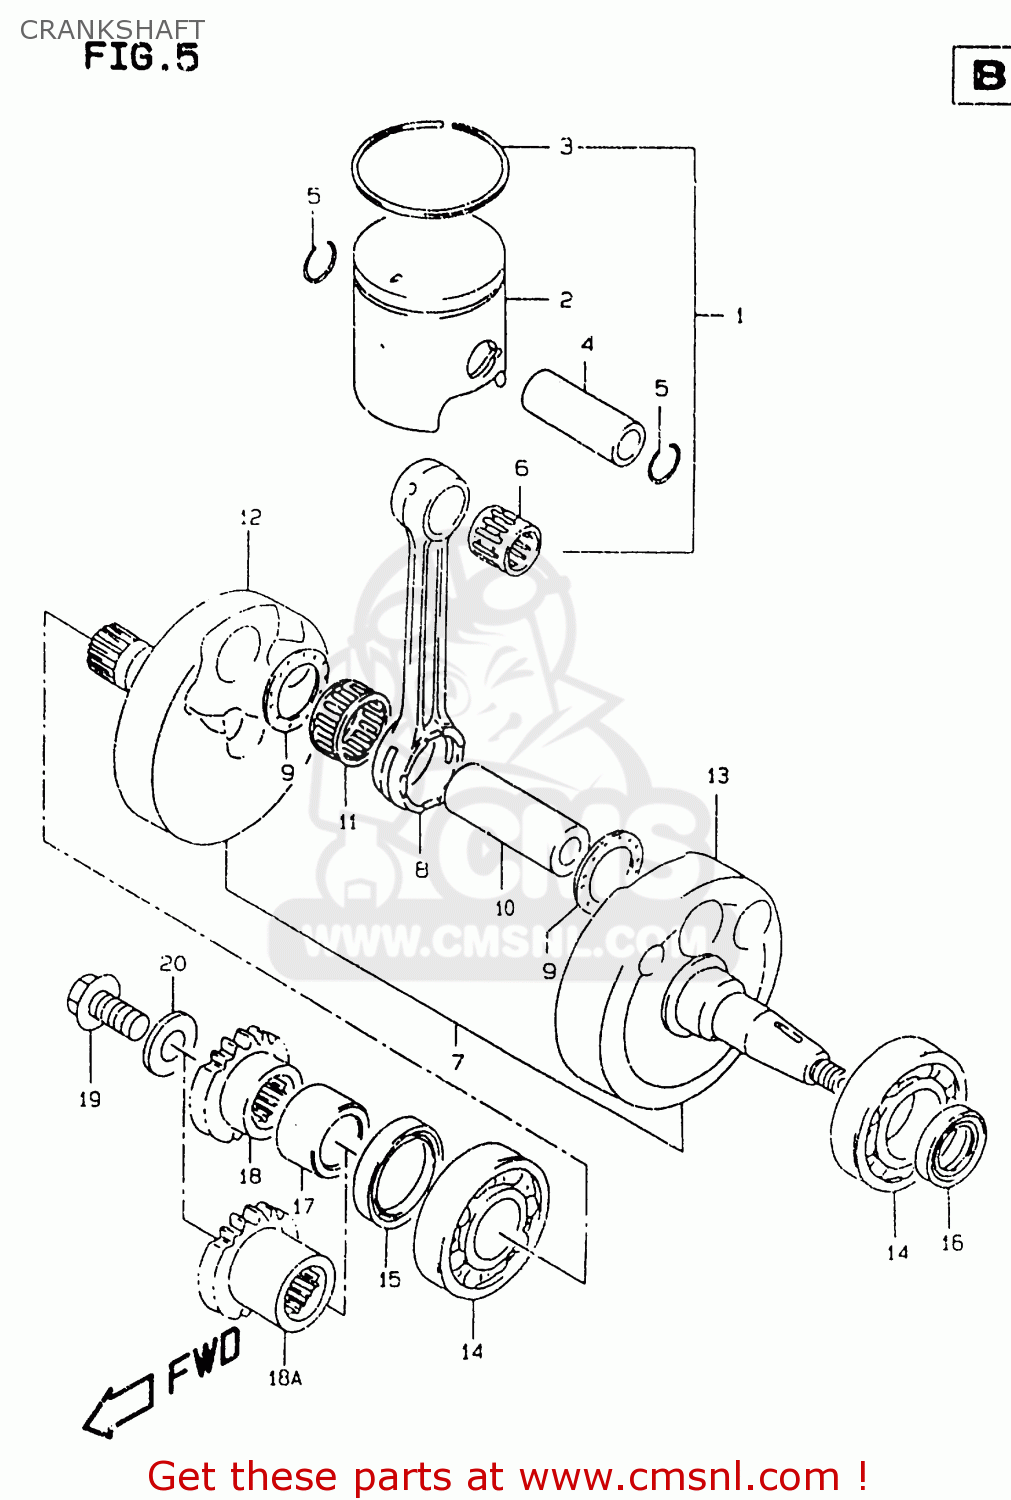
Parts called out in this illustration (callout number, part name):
1	PISTON KIT
2	PISTON
3	RING,PISTON
4	PIN,PISTON
5	CIRCLIP
6	BEARING(15X19X20)
7	CRANKSHAFT ASSY
8	ROD,CONNECTING
9	WASHER(22X36X1.5)
10	PIN,CRANK
11	BEARING(22X28X16)
12	CRANKSHAFT,R
13	CRANKSHAFT,L
14	BEARING(22X56X16)
15	SEAL,OIL(30X40X7)
16	SEAL,OIL(18X30X6)
17	SPACER,PRIMARY DRIVE GEAR
18	GEAR,PRIMARY DRIVE (NT:
18A	GEAR,PRIMARY DRIVE
19	BOLT,PRIMARY DRIVE GEAR
20	WASHER
